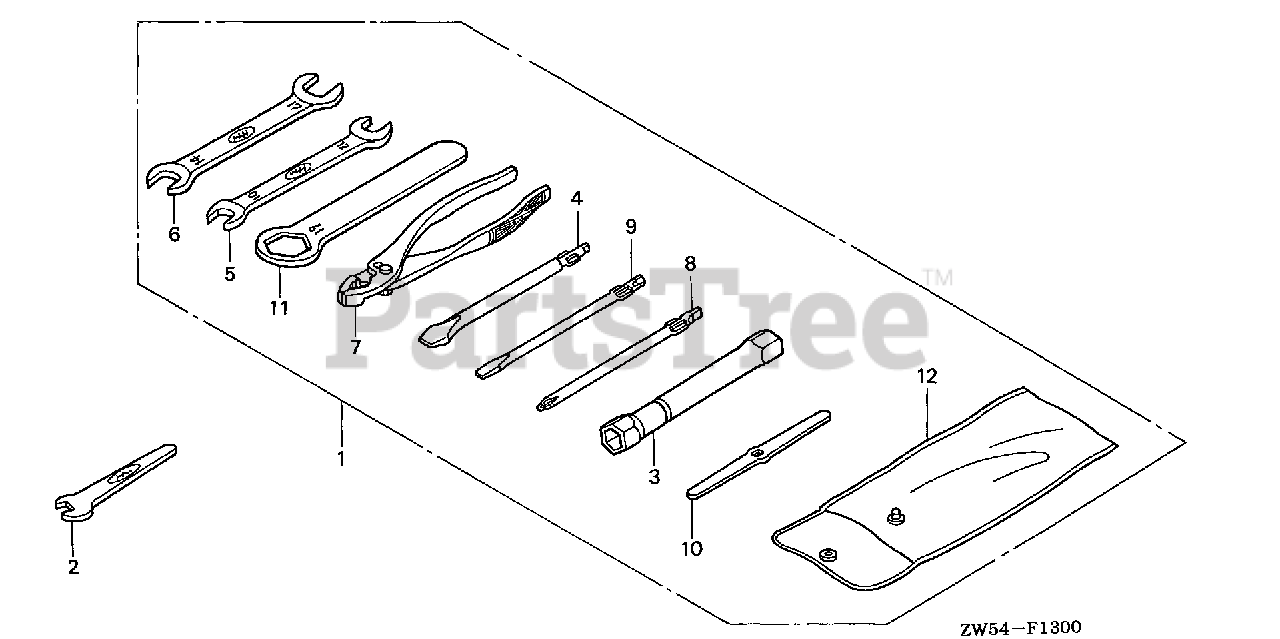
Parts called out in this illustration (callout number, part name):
2	SPANNER (8MM) (NOT AVAILABLE)
3	WRENCH, PLUG
4	SCREWDRIVER, CHECK BOLT
5	SPANNER (10X12)
6	SPANNER (14X17)
7	PLIERS (135) (KOWA)
7	PLIERS (135)
8	DRIVER 1, PLUS SCREW (NO.2)
9	DRIVER 3, MINUS SCREW (NO.2)
11	WRENCH, EYE (19MM)
